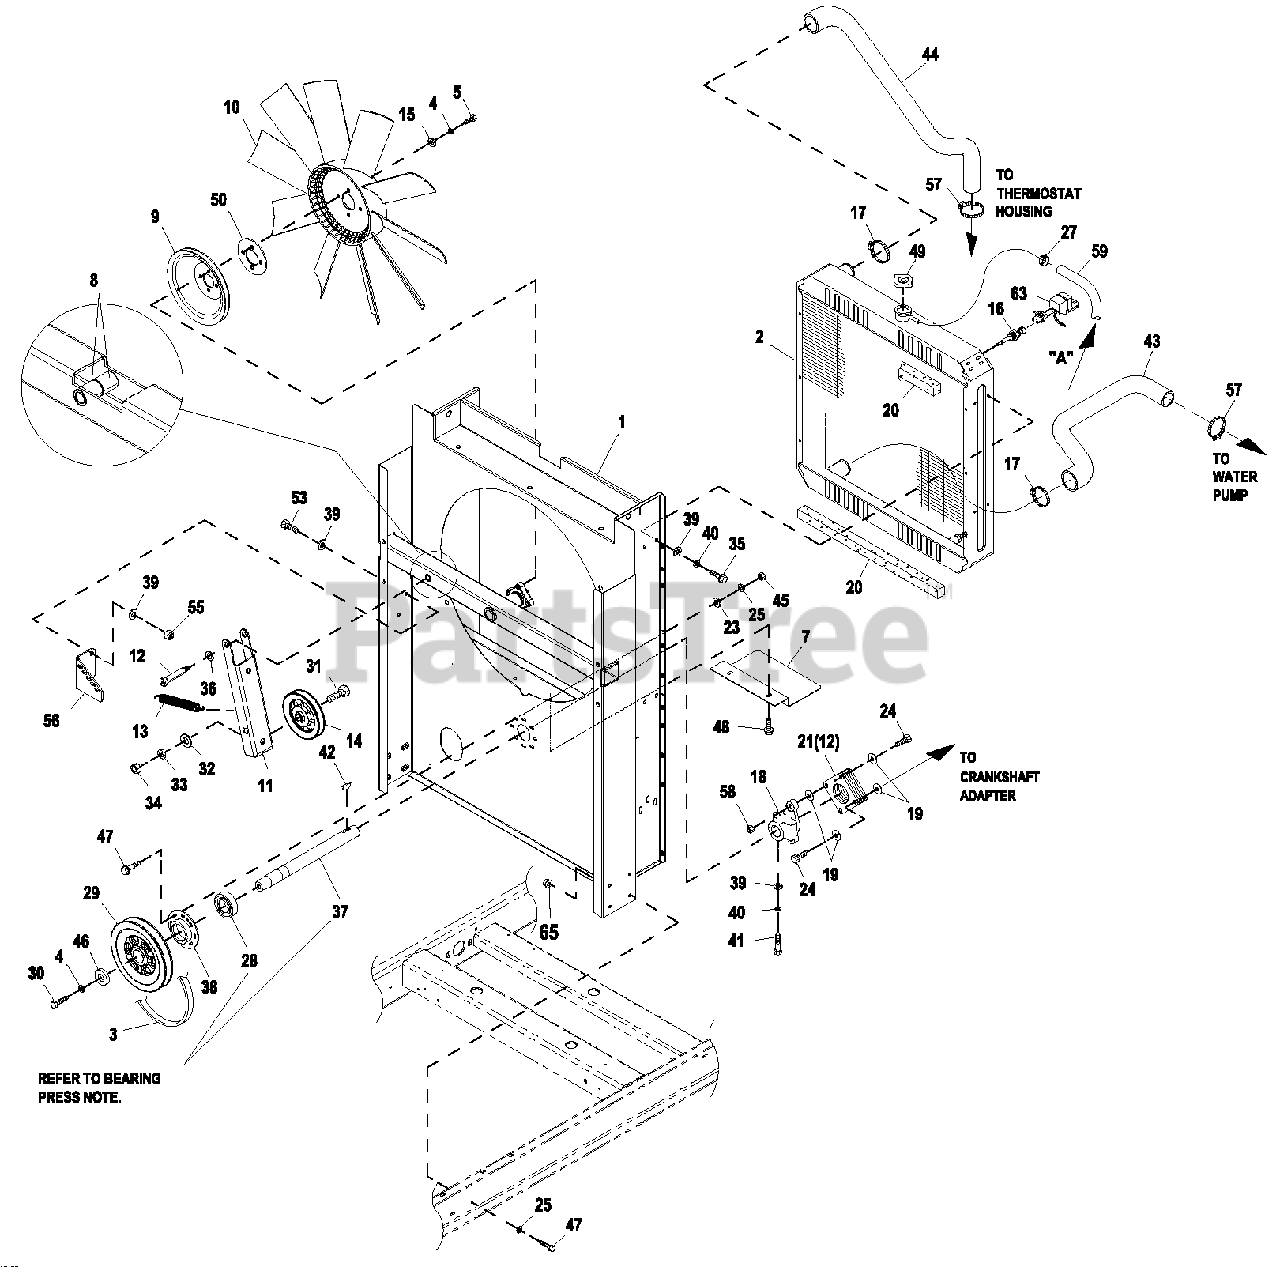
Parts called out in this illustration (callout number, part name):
1	WELDMENT RADIATOR SUPPORT C2
2	RADIATOR 598 X 568 X 49 CPL RH
3	V-BELT A58 (60IN O.C.) DDC S60
4	WASHER LOCK M10
5	SCREW HHC M10-1.5X 30 G10.9
6	HOSE 2"ID X 3.0"LG
7	SHIELD RADIATOR C4
8	BEARING SLEEVE 1/2/X 3/4X1
9	PULLEY FAN V-GROOVE 9"
10	FAN COOL 22" DIA 10 BLADE LH
11	ARM BELT TENSIONER
12	SHOULDER BOLT 1/2 X 2-1/4"
13	SPRING TENSION CPL
14	PULLEY V-BELT 4" FLANGED
15	WASHER FLAT 3/8-M10 ZINC
16	PROBE COOLANT LEVEL 3/8 NPTF
17	CLAMP HOSE #28 1.32-2.25
18	HUB FLEX PLATE
19	WASHER FLEX (THIN)
20	TAPE FOAM 1 X 1 (26.75" LG)
21	DISK FLEX
22	BRACKET COOLANT TANK
23	WASHER FLAT 1/4-M6 ZINC
24	SCREW HHC 5/16-24X1.124
25	WASHER LOCK M6-1/4
26	TANK COOLANT RECOVERY
27	CLAMP HOSE BAND 1/4
28	BEARING #6205 2NSE C3 E SRI2 S
29	PULLEY 7.5" DIA MACHINED
30	SCREW HHC M10-1.5X30 G8.8
31	SCREW HHC 1/2-13X2" G8
32	WASHER FLAT 1/2 ZINC
33	WASHER LOCK 1/2
34	NUT HEX 1/2-13 STEEL
35	SCREW HHFC M8-1.25 X 20 W/M6
36	WASHER NYLON .50 X .87 X .06
37	SHAFT FAN DRIVE
38	RETAINER BEARING
39	WASHER FLAT 5/16-M8ZINC
40	WASHER LOCK M8-5/16
41	SCREW HHC M8-1.25X 45 C8.8
42	KEY WOODRUFF 4 X19D
43	HOSE LOWER RADIATOR G2
44	HOSE UPPER RADIATOR G2 (USED WITH MANFLD P/N 0G0707)
45	NUT HEX M 6X1.0 G8 YELCHR
46	SPACER .5X1.5X.25STL/ZINC
47	SCREW HHFC M6-1.0X 2 0 G8.8
48	SCREW THF M6-1 X 16 N WA Z/JS
49	CAP RADIATOR 13 PSI
50	SPACER CPL COOLING FAN 1/8"
51	SCREW THF M6-1 X 30 N WA DELTA
52	TUBE CAC OUT G2 TURBO
53	SCREW HHC M8-1.25X20 C8.8
54	TUBE CAC IN
55	NUT HEX LOCK M8-1.25 NY INS
56	BRACKET TENSIONER SPRING
57	CLAMP HOSE #24 B1.06-2.00
58	NUT HEX LOCK 5/16-24 NY INS
59	HOSE 9/32 ID (36"LG)
60	CAC 504W X 152H X50D 2.4L G2
61	CLAMP CNST TENSION 1.75-2.625
62	HOSE 2"ID X 3.0"LG
63	ASSY PCB LCL SENSOR (USE WITH I/N 16, P/N 0H1827 ONLY)
65	NUT FLANGE M6-1.0 NYLOK
66	CLAMP HOSE BAND .50
67	HOSE 9/32 ID (27"LG)
